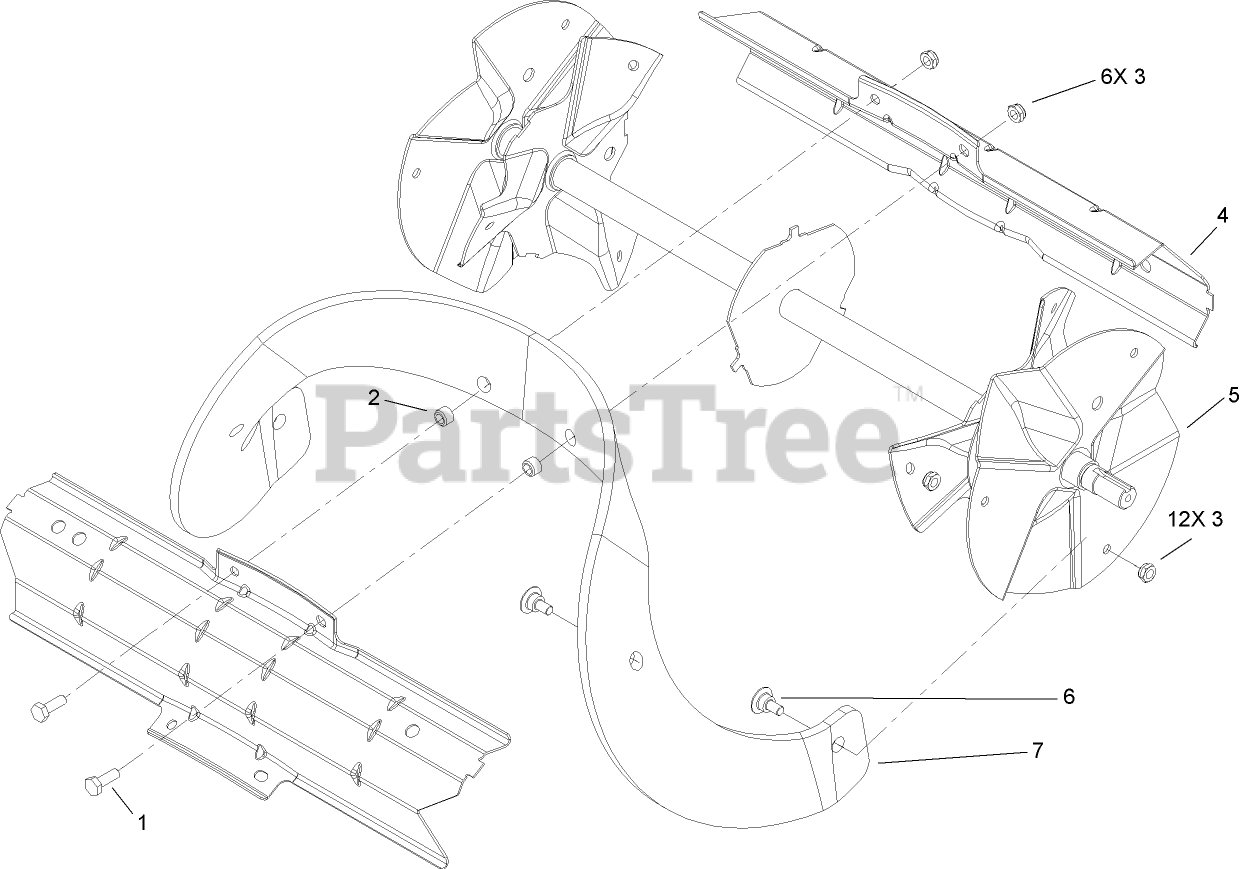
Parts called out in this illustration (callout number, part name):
1	SCREW-HH
2	SPACER-BLADE, ROTOR
3	NUT-LOCK, NI
4	DRUM-ROTOR
5	ROTOR ASM
6	SCREW
7	BLADE-ROTOR
